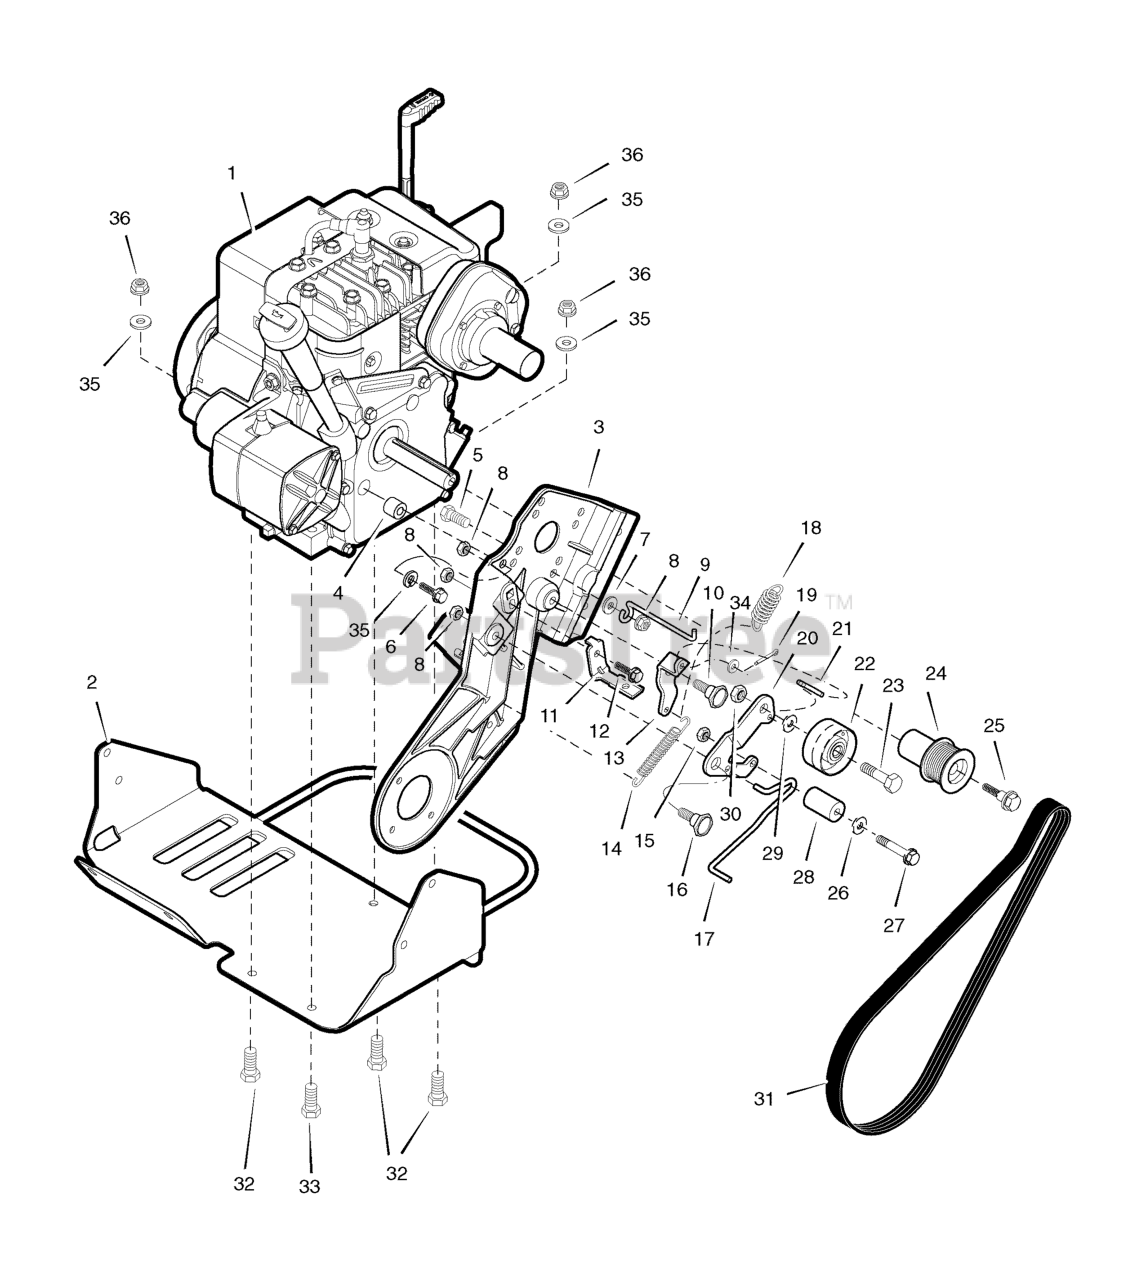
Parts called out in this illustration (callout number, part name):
1	Engine
2	Cradle Assy, Engine
3	Frame, Left
4	Mount, Antivibration
5	Bolt 5/16-18x 0865
6	Bolt 5/16-24x1.125
7	Washer, Flat
8	Locknut 5/16-18
9	Guide, Belt
11	Pad, Brake
12	Screw, 1/4-20 x .63
13	Idler, Arm Pivot
15	Nut Hex 1/4-20
17	Wire, Brake
19	Pin, Cotter
20	Arm, Idler
21	Rod, Clutch Linkage
22	Pulley, Idler
23	Screw, 3/8-16 x 1.50
24	Pulley, Engine
25	Bolt, Engine Pulley
26	Washer, Flat
27	Screw, 1/4-20 x 2.00
28	Pinch Roller
29	Washer, Flat
30	Nut, Hex
31	Belt, Drive
32	Bolt, Hex 5/16-18X1.625
33	Screw 3/8-16X1.00
34	Washer, Flat
35	Lockwasher, Split
36	Nut 5/16-18
